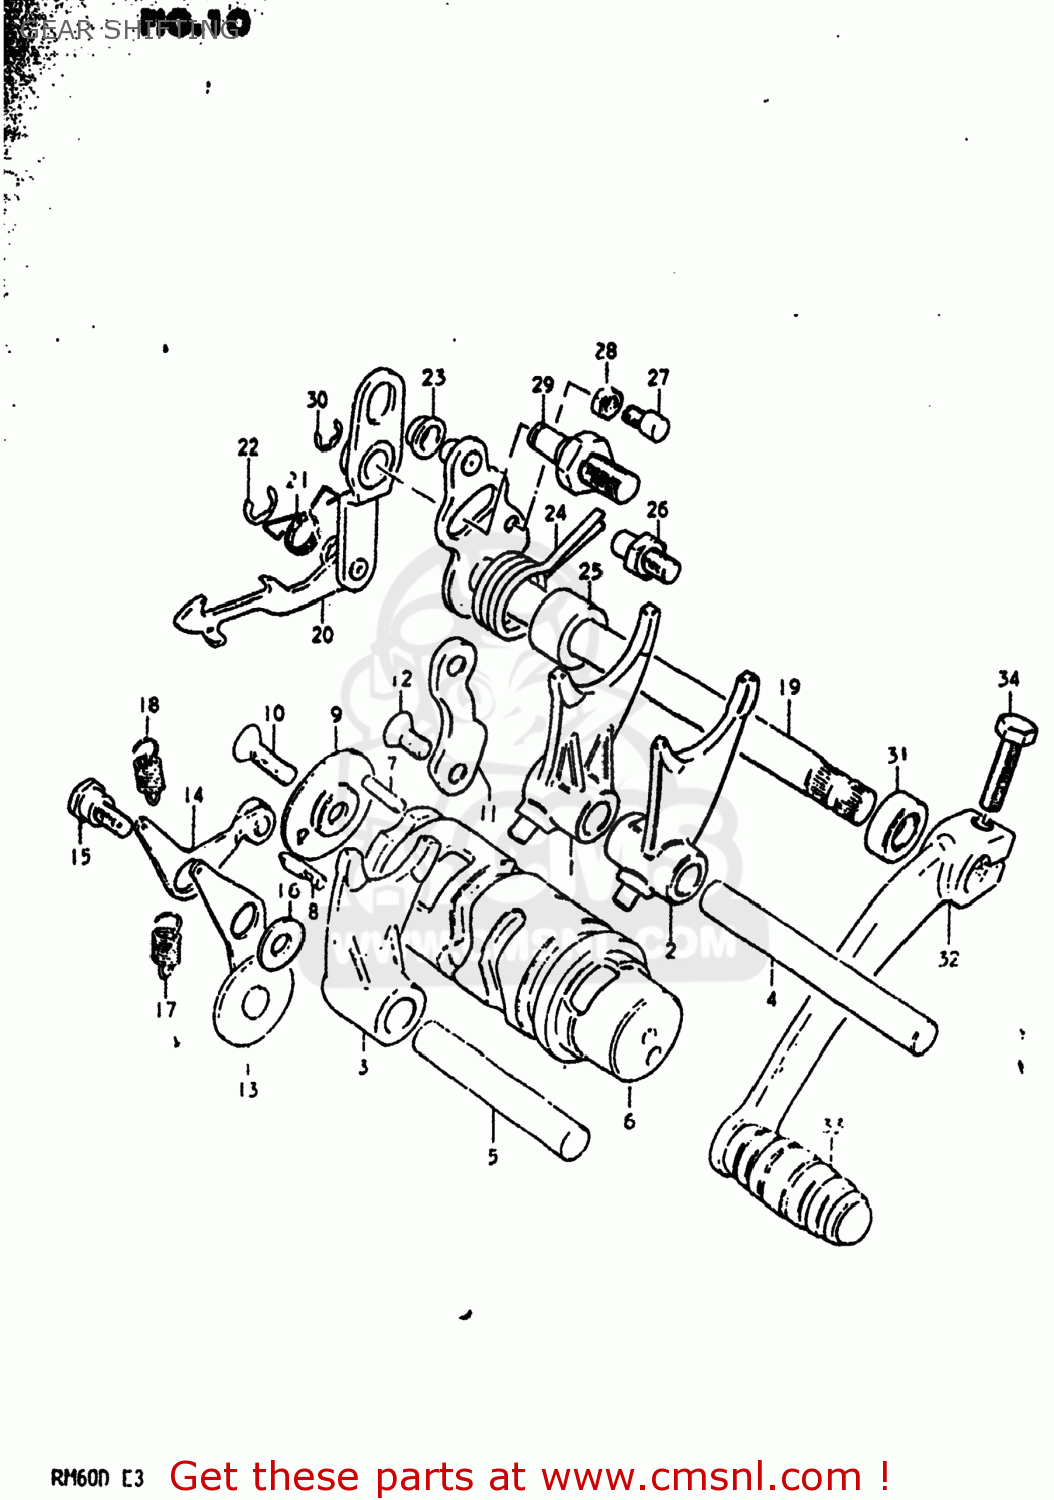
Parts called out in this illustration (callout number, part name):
1	FORK,GEAR SHIFT NO.1
2	FORK,GEAR SHIFT NO.2
3	FORK,GEAR SHIFT NO.2
4	SHAFT,GEAR SHIFT FORK
5	SHAFT,GEAR SHIFT FORK
6	CAM,GEAR SHIFT
7	PIN(4X15.8)
8	PIN
9	RETAINER,GEAR SHIFT CAM
10	SCREW
11	GUIDE,GEAR SHIFTING CABLE
12	SCREW
13	STOPPER,GEAR SHIFTING
14	STOPPER,GEAR SHIFT CAM
15	BOLT(6X18.3)
16	WASHER (6.5X13X2.3)
17	SPRING
18	SPRING
19	SHAFT,GEAR SHIFT
20	PAWL,GEAR SHIFT
21	SPRING
22	E RING
23	SPACER(7X10X5)
24	SPRING
25	SPACER(12X20X15.3)
26	STOPPER,GEAR SHIFT CAM
27	BOLT,GEAR SHAFT RETURN SPR SET
28	NUT 6MM
29	STOPPER,GEAR SHIFT CAM
30	E RING 6MM
31	OIL SEAL
32	LEVER ASSEMBLY,GEAR SHIFTING
33	RUBBER,GEAR SHIFT PEDAL
34	BOLT
